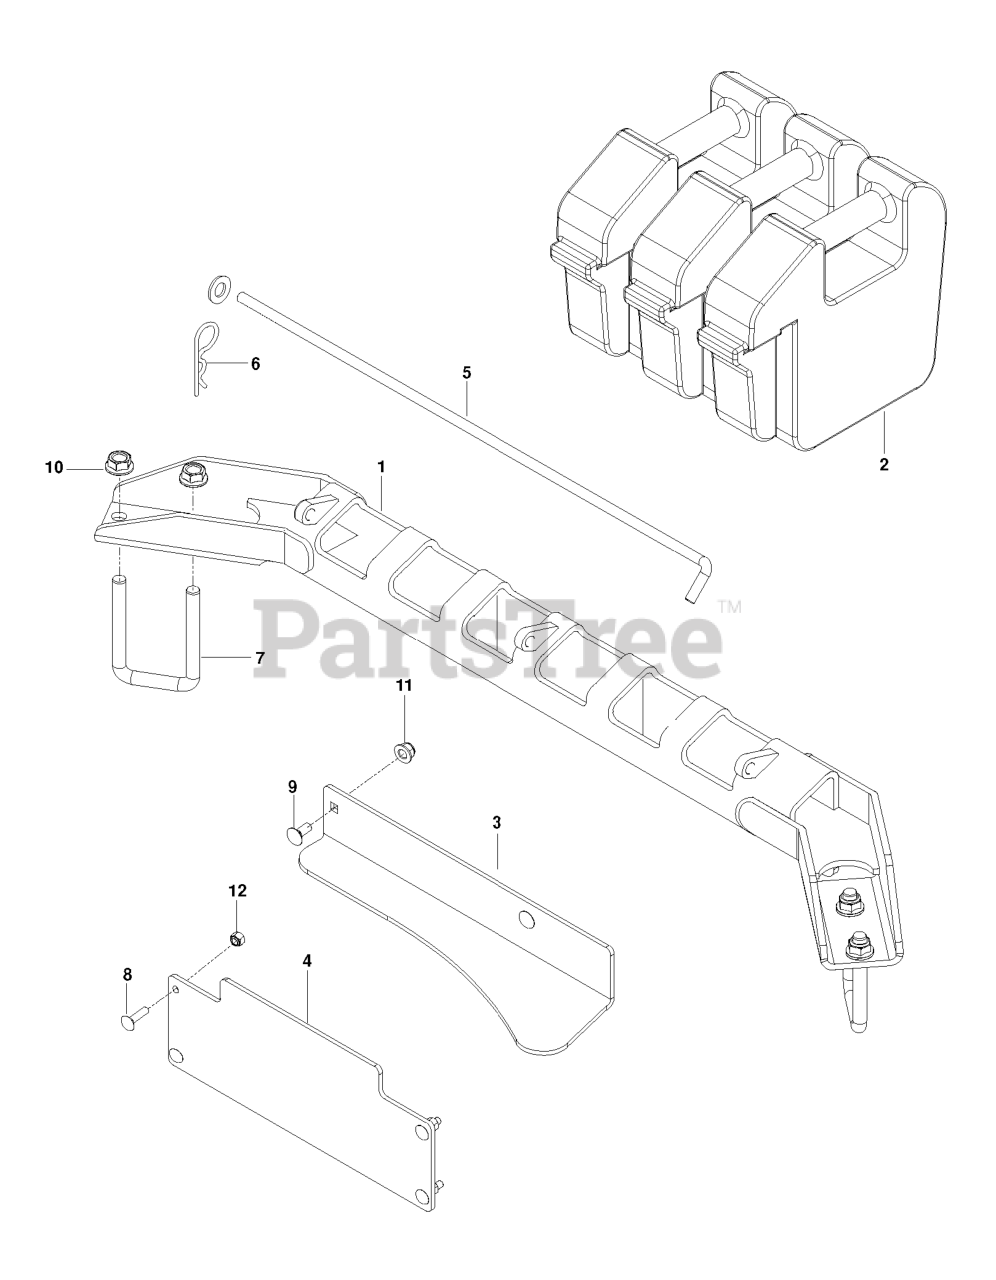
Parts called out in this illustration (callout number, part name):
1	BRACKET.MTG.CNTRWT.SIX.BLK
2	FRONT WEIGHT CAST PZ DFS
3	BAFFLE, RH, BLACK
4	BAFFLE, LH, BLACK
5	ROD.LATCH.BLK
6	HAIRPIN #4
7	U-BOLT.SQUARE.1/2-13.GR5
8	RHSNB, 1/4-20 X 1, GR5
9	RP BOLT 5/16-18 X3/4 ZN/YEL GR
10	NUT, 1/2-13 HEX FLG NYLOC ZD
11	5/16-18 NYLOC FLANGE NUT
12	LOCKNUT.NYLOC.1/4-20
